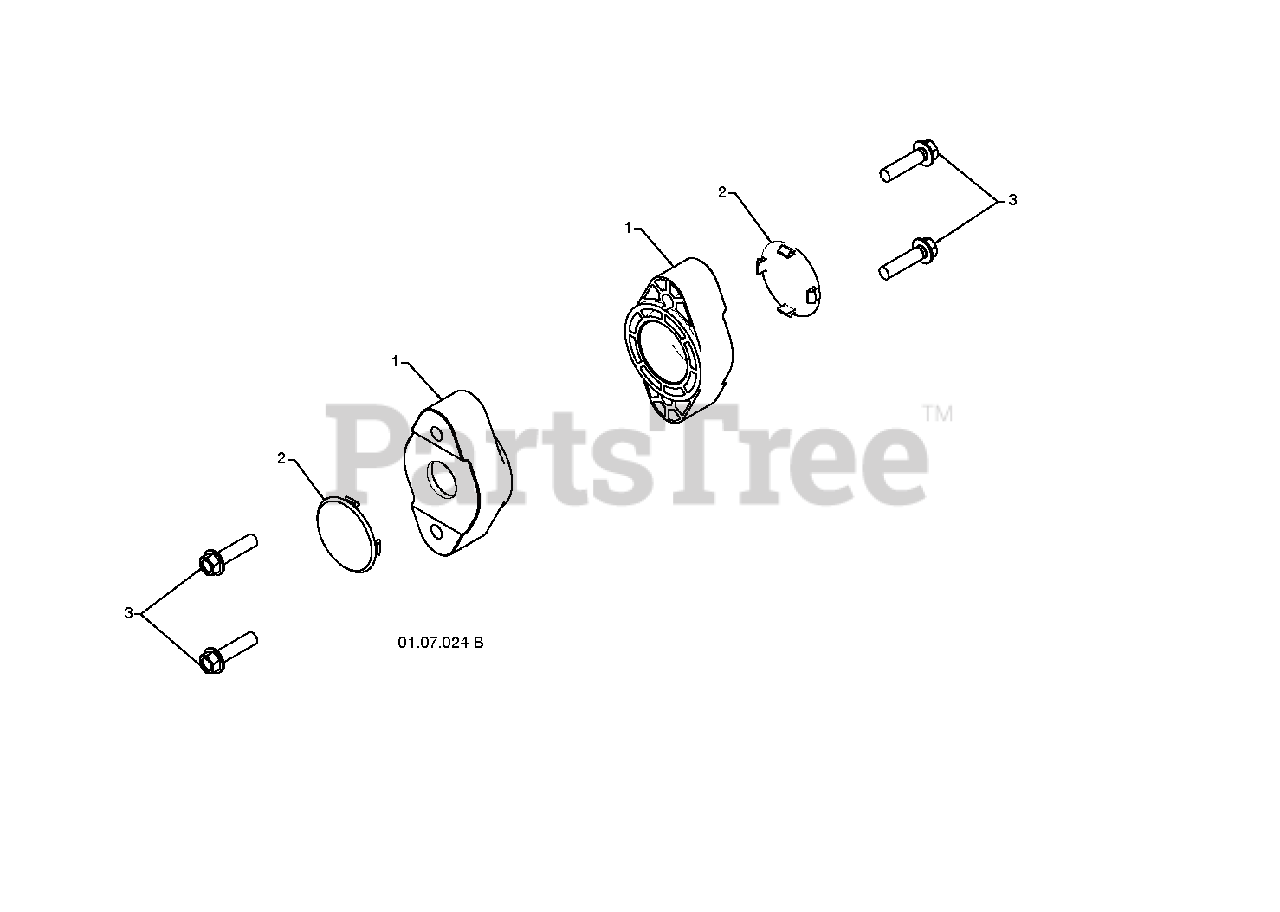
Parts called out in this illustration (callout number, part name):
1	BEARING.AUGER.SHAFT
2	PLUG.BEARING.HOLE.HSG
3	SCREW, HEX HD 5/16X1
